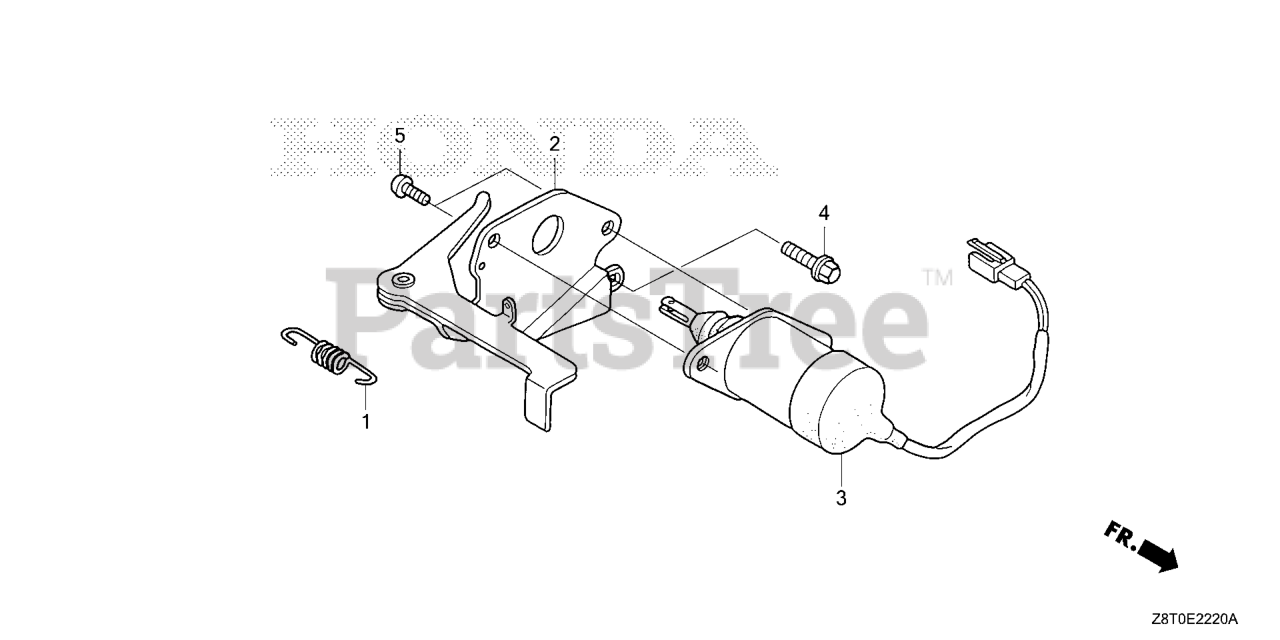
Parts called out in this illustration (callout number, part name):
1	SPRING, CHOKE RETURN
2	LEVER, THROTTLE
3	SOLENOID ASSY.
4	BOLT, FLANGE (6X12) (CT200)
5	SCREW, PAN (5X8)
